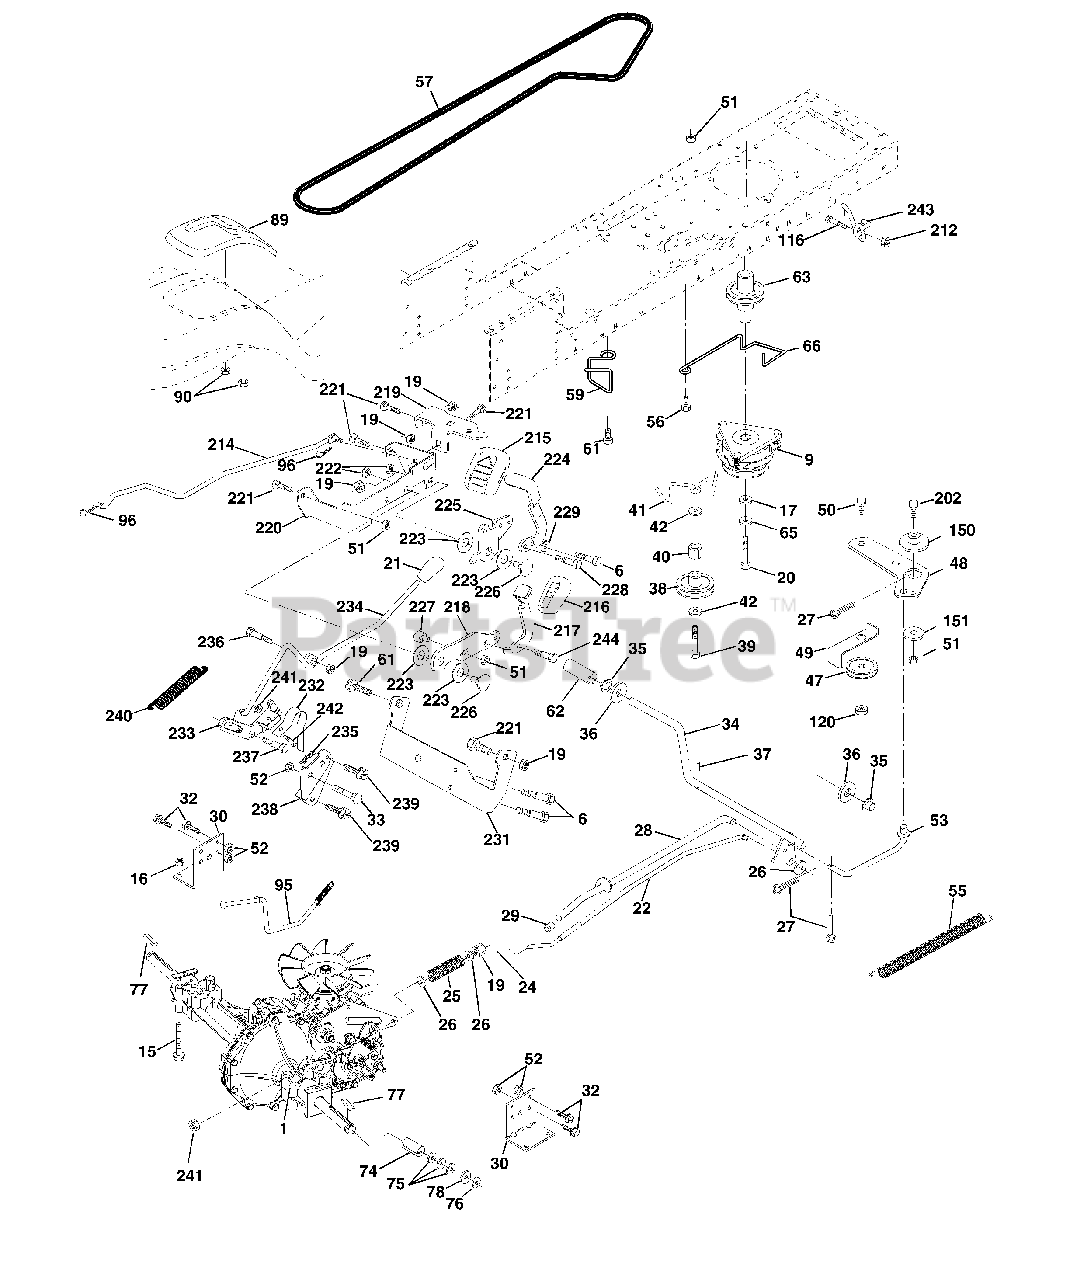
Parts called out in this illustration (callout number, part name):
1	Transaxle
9	Clutch Elec
15	Bolt Hex Flghd 5/16-18 Gr. 5
16	Nut Lock Hex W/Ins. 5/16-18 Unc
17	Washer 1-1/2 OD x 15/32 ID x .250
19	Nut Lock Hex W/Wsh 3/8-16 Unc
20	Bolt Hex 7/16-20 x 4 x Gr. 5-1.5
21	Knob Custom Control Cruise
22	Rod, Brake
24	Nut, Hex Jam 3/8-16 Unc
25	Spring, Brake Rod
26	Washer
27	Pin Cotter 1/8 x 3/4 CAD.
28	Rod, Parking Brake
29	Cap, Brake, Park
30	Bracket, Transaxle
32	Bolt Hex Hd 5/16-18 Unc x 3/4
33	Bolt Rdhd Sqnk 5/16-18 Unc x 3/4
34	Shaft, Foot Pedal
35	Bearing, Nylon
36	Washer
37	Pin, Roll
38	Pulley, Composite, Flat
39	Bolt Fin Hex 3/8-16 Unc x 3
40	Spacer, Split
41	Keeper, Belt Idler Flat
42	Washer 13/32 x 13/16 x 12 Ga.
47	Pulley, Idler, V-Groove
48	Bellcrank Clutch Grnd Drw Stl
49	Retainer, Belt
50	Bolt
51	Nut Crownlock 3/8-16 UNC
52	Nut, Crownlock 5/16-18 Unc
53	Link, Clutch
55	Spring, Return, Clutch
56	Screw 3/8-16 x 1.0
57	V-Belt, Ground Drive
59	Keeper, Center Span
61	Screw 3/8-16 x 3/4
62	Cover, Pedal
63	Pulley, Engine
65	Washer
66	Keeper Belt Engine
74	Spacer, Axle
75	Washer 25/32 x 1-1/4 x 16 Ga.
76	E-Ring
77	Key, Square
78	Washer 25/32 x 1-5/8 x 16 Ga.
89	Console, Shift
90	Nut Self-Thd Wsh-hd 1/4 Zinc
95	Rod Bypass
96	Retainer Spring 1" Zinc/Cad
116	Bolt RDHD SQNK 3/8-16 Unc x 1
120	Nut Lock Flg 3/8-16 Unc
150	Spacer Retainer
151	Washer 13/32 x 2 x 10 Ga.
202	Bolt Carr Sh 3/8-16 x 1-1/2 Gr. 5
212	Nut Hex Flange Lock
214	Link Transaxle
215	Cover Pedal Forward
216	Cover Pedal Reverse
217	Pedal Reverse
218	Arm Control Pedal Reverse
219	Bracket Frest Pdl Ctrl. Hyd
220	Bracket Mtg. Pedal Control
221	Bolt Rdhd Sqnk 3/8-16 Unc x 3/4
222	Nut Crownlock 7/16-14 Unc
223	Washer Nylon 11/16 ID x .060
224	Pedal Forward
225	Arm Control Pedal Forward
226	Bolt Pivot Spacer
227	Cam Reverse Pedal LT
228	Bolt Shoulder 5/16-18
229	Washer Serrated 5/16 x .75
230	Screw 5/16-18
231	Strap Torque
232	Actuator Cruise Disengage
233	Pawl Control Cruise
234	Lever Control Cruise
235	Sector Control Cruise
236	Bolt Shoulder 3/8-16 Unc 1/44
237	Bolt Shoulder 5/16-18
238	Arm Mtg. Cruise Sector
239	Screw Thdrol 5/16 x 1/2
240	Spring Return Cruise Control
241	Nut Centerlock 1/4-20 Unc
242	Bolt Fin Hex 1/4-20 Unc x 1/2
243	Bracket Anti-Rotation CVX
244	Screw 5/16-18 x 1/2
